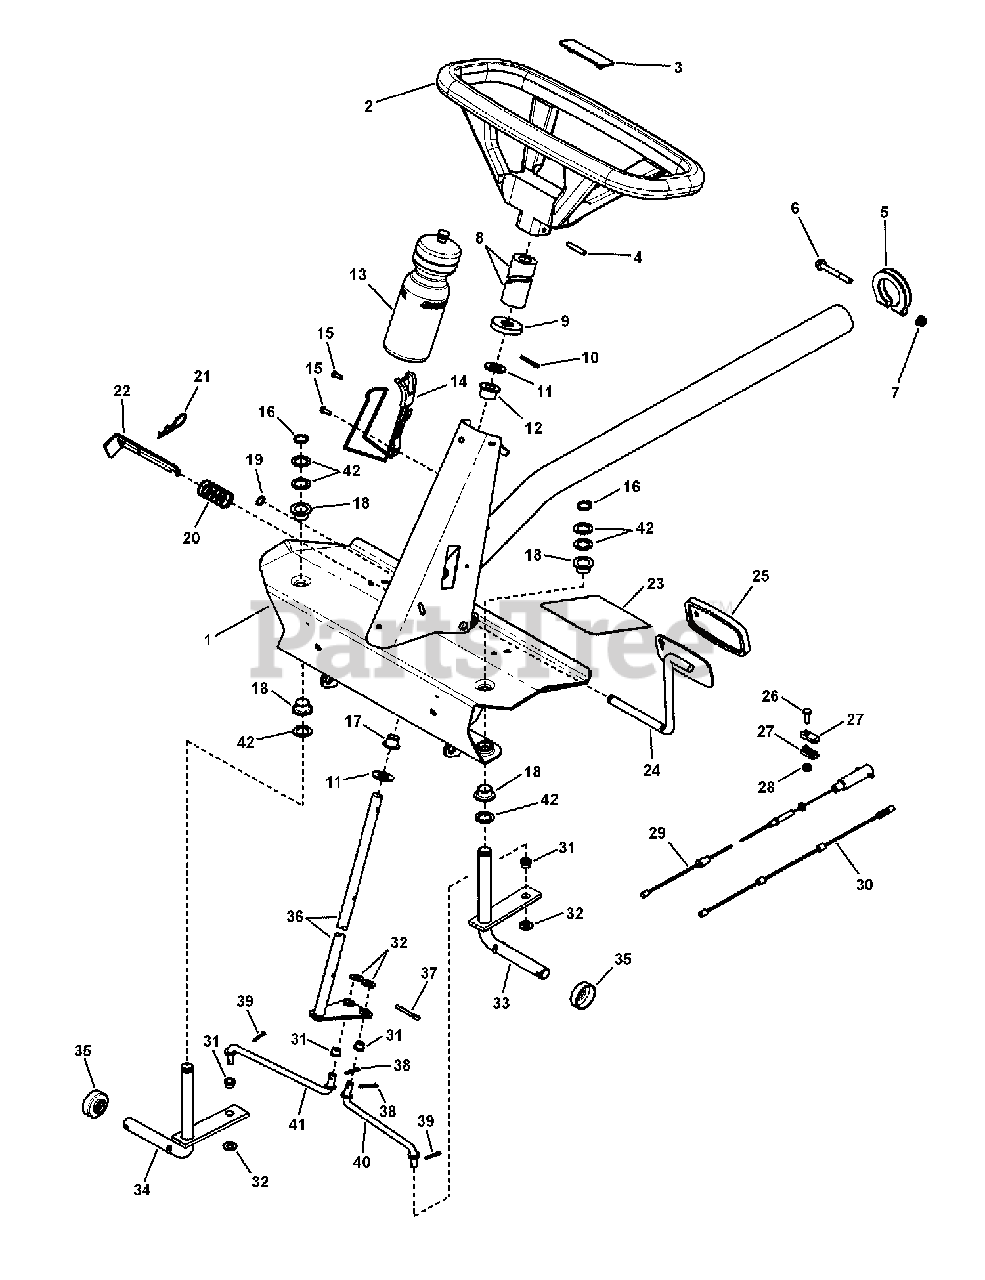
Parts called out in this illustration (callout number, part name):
1	WELDMENT, Front Axle, Narrow
2	ASSEMBLY, Steering Wheel (for 5/8 shaft)
3	LOGO, Steering Wheel
4	ROLL PIN, 1/4 x 1-1/2"
5	TUBE CLAMP
6	SCREW, 5/16-24 x 2-1/2 Hex Head Cap, GR 5
7	NUT, 5/16-24 Flange Lock (Large)
8	FOAM COVER, Steering Shaft
9	COVER, Steering Shaft
10	PIN, 3/16 x 1 Cotter
11	WASHER, .66 x 1.31 x .09 Flat
12	BUSHING, Nylon
13	BOTTLE, Water
14	HOLDER, Bottle (Wire)
15	SCREW, #10-24 x 1/2 Hex Washer Self-Tap (Torx)
16	RING, 5/8 External Retaining
17	BUSHING, Nylon
18	BEARING, Nylon
19	RING, 1/2 External Retaining (Heavy Duty)
20	SPRING, Parking Brake Latch
21	HAIR PIN 2-1/4
22	LATCH, Parking Brake
23	FOOT PAD, Short (5.5 x 4.7)
24	WELDMENT, Clutch Pedal
25	PAD, Pedal
26	HHCS, 1/4-20 X 0.750, GR5 Zinc/Clear
27	CONNECTOR, Cable
28	NUT, 1/4-20 Hex Center Lock, GR 5 or B
29	CABLE, Brake, Snap-In
30	CABLE, Clutch/Brake (54.32 long)
31	BUSHING, Tie Rod
32	WASHER, 3/8 Flat SAE
33	WELDMENT, King Pin, Left Hand
34	WELDMENT, King Pin, Right Hand
35	CAP, Dust
36	WELDMENT, Steering Shaft
37	PIN, 3/16 x 1-1/2 Cotter
38	PIN, 5/32 x 1 Cotter
39	PIN, 1/8 x 3/4 Cotter
40	TIE ROD, Left Hand (7.41 long)
41	TIE ROD, Right Hand (7.41 long)
42	WASHER, .77 x 1.13 x .06 Flat
